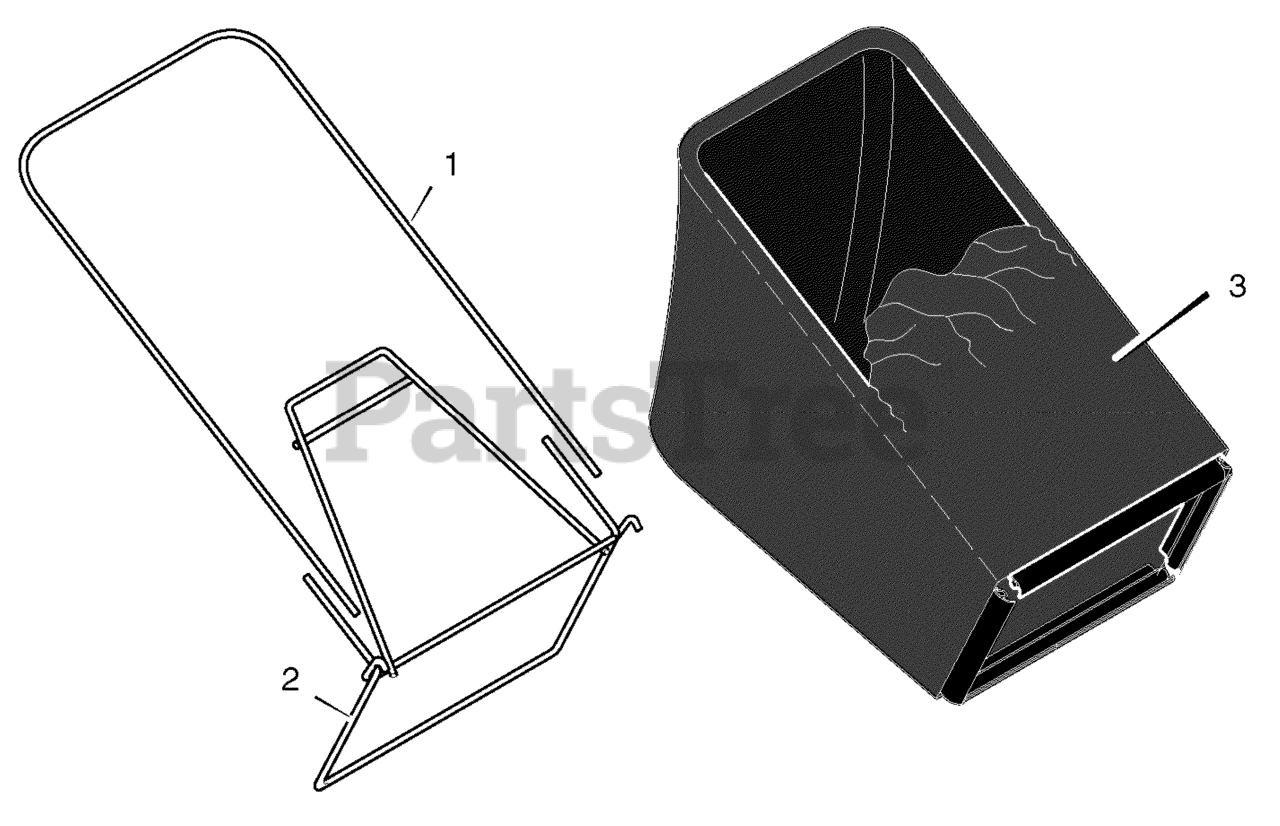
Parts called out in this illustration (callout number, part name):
1	Tube, Bag
2	Frame Assembly
3	Bag, Cloth -Black
